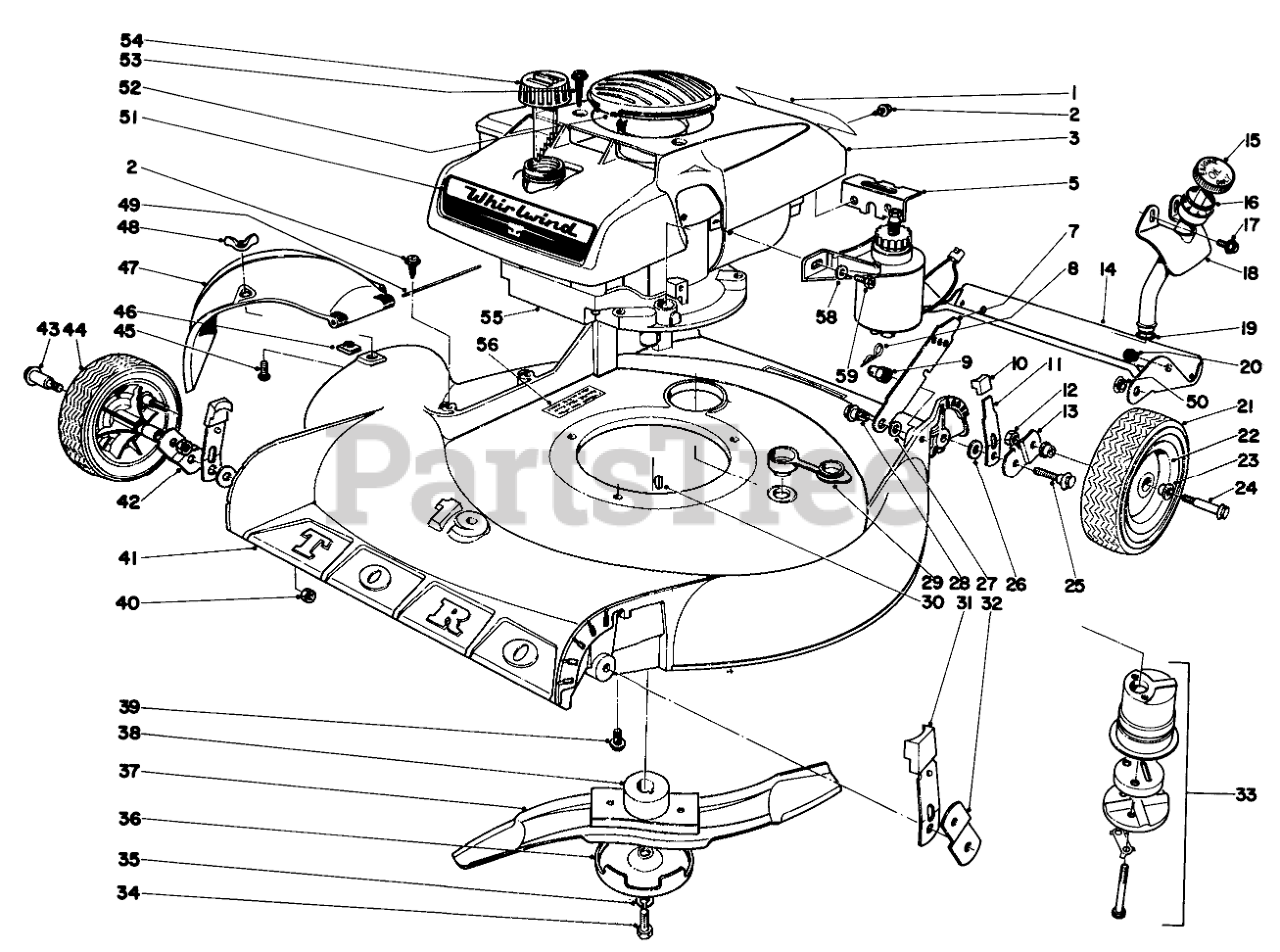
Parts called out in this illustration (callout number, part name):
1	Decal,Maintenance
2	SCREW-HWHTF
3	Shroud
5	Bracket
7	Latch
8	PIN-COTTER, HAIR
9	Nut
11	Spring Arm
12	Nut
13	Pivot Arm
14	REAR SAFETY SHIELD
15	Dipstick
16	O-Ring
18	Oiler Tube
19	O-RING
20	SKID BUTTON
21	8 TIRE
22	Wheel, (Incl. Ref. No. 23)
23	Bushing
24	Wheel Bolt
25	Pivot Screw
26	WASHER-PIVOT
27	SPACER
28	SCREW-SHOULDER
29	Washer Plug
30	KEY-WOODRUFF
31	ARM KNOB
32	Pivot Arm
33	MUFFLER KIT
34	SPECIAL SCREW
35	WASHER-LOCK
36	ANTI-SCALP CUP
37	Blade
38	BLADE RETAINER WA
39	Screw
40	Nut
41	Housing
42	Pivot Arm
46	NUT-SPEED
47	Deflector
48	NUT-WING SPECL
49	HINGE PIN
50	Nyliner
51	Decal
52	Insert Shroud
53	SCREW-HWH
54	Gas Cap
55	Engine
56	Decal
58	WASHER-FLAT
59	SCREW-HH
